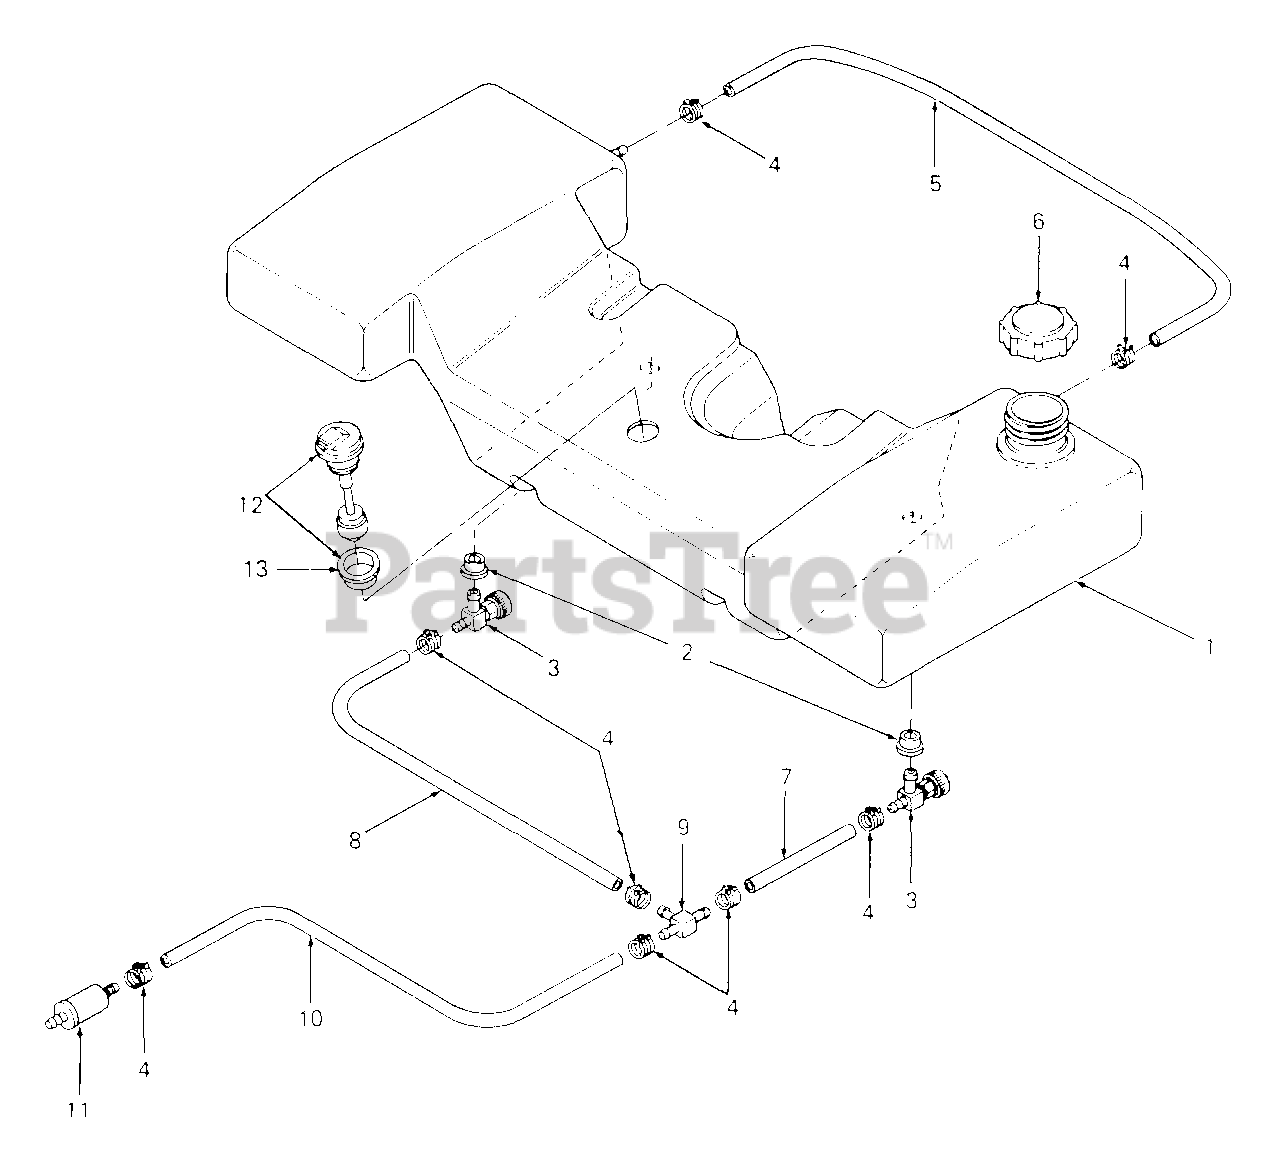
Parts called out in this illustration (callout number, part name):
1	Tank, Fuel
2	Bushing
3	Valve, Fuel Shutoff
4	Clamp, Hose
5	Line, Fuel - 24" Lg
6	Cap, Fuel
7	Line, Fuel - 5" Lg
8	Line, Fuel - 17" Lg
9	T-Fitting
10	Line, Fuel - 41" Lg
11	Filter, Fuel
12	Sensor, Low Fuel
13	Bushing, Rubber
